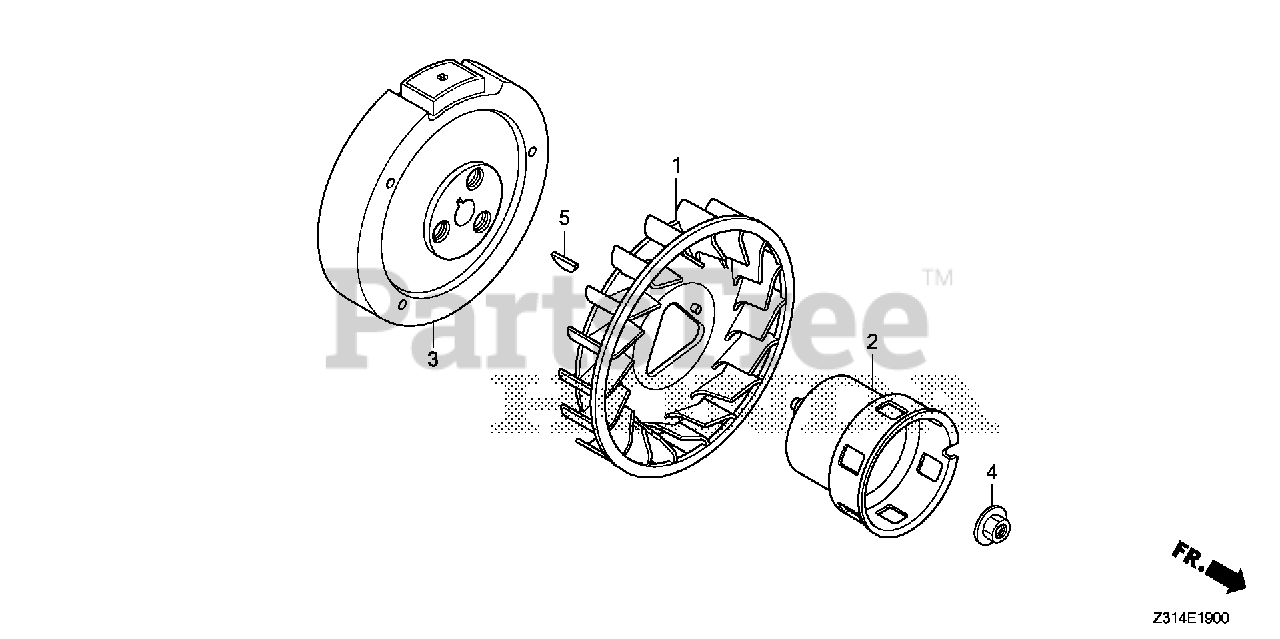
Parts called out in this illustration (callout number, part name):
1	FAN, COOLING
2	PULLEY, STARTER
3	FLYWHEEL (LAMP)
4	NUT, SPECIAL (16MM)
5	KEY, SPECIAL WOODRUFF (25X18)
